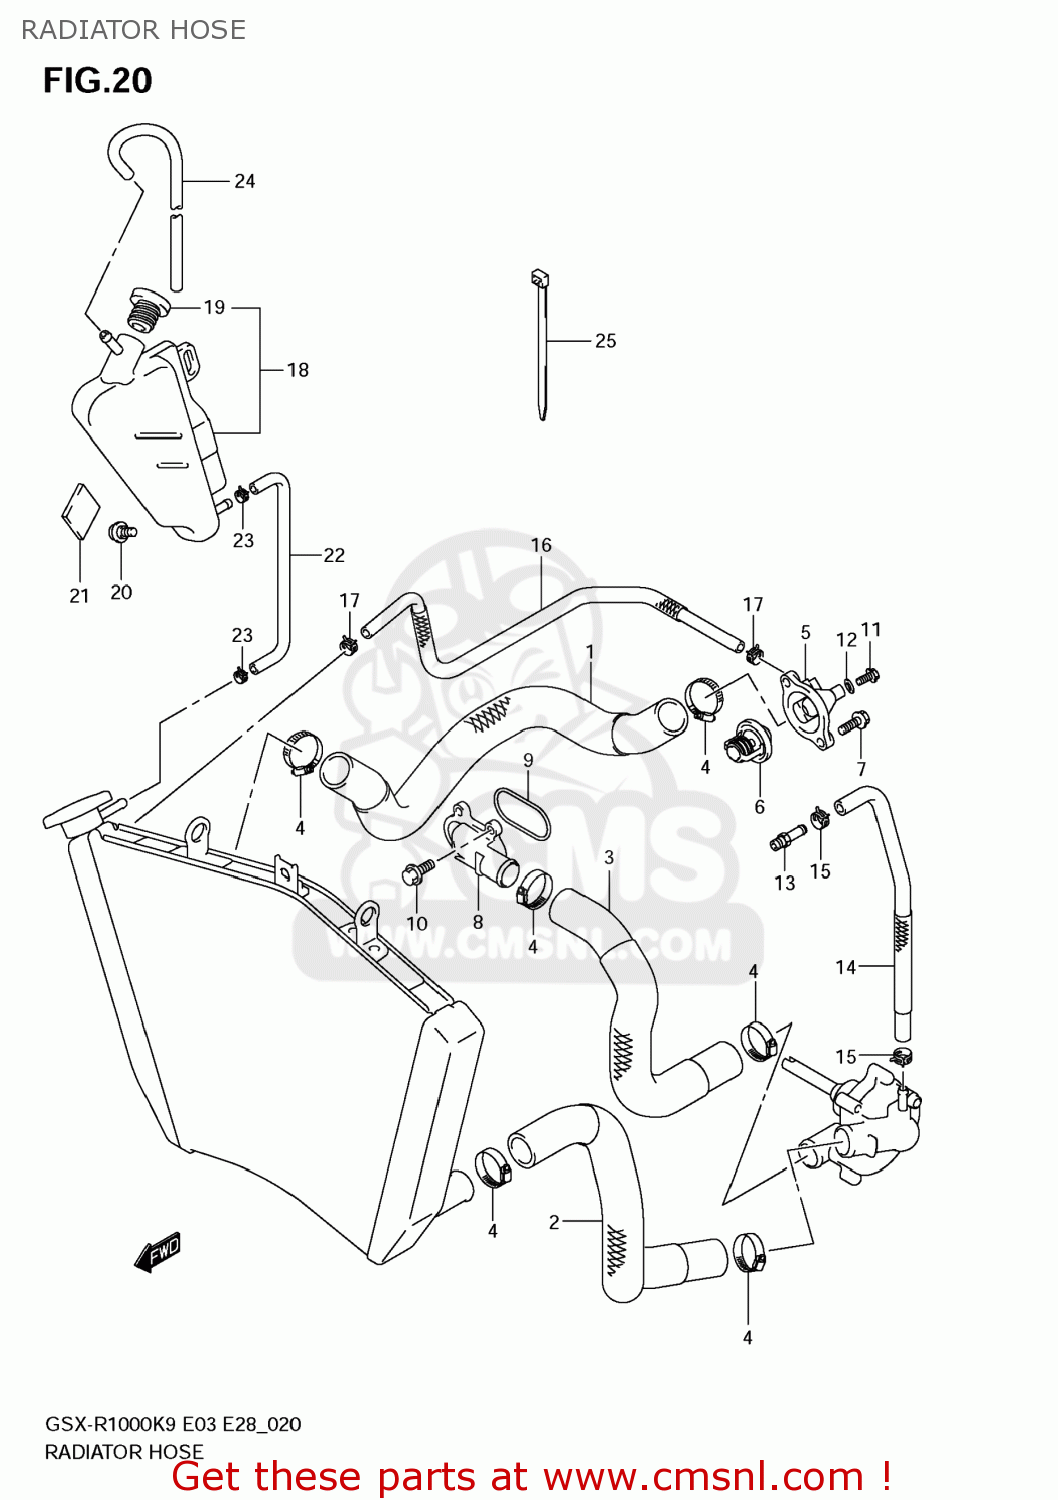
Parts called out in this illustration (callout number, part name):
1	HOSE,RADIATOR INLET
2	HOSE,RADIATOR OUTLET
3	HOSE,CYLINDER INLET
4	CLAMP
5	COVER,THERMOSTAT
6	THERMOSTAT,WATER
7	BOLT
8	CONNECTOR,CYLINDER WATER INLET
9	O RING,CYL WATER CONNECTOR
10	BOLT
11	UNION BOLT,AIR VENT
12	GASKET(6.4X11.5X0.8) (NAS)
13	BOLT UNION
14	HOSE,WATER BYPASS
15	CLAMP
16	HOSE,WATER AIR BLEED
17	CLIP
18	TANK ASSY,RESERVOIR
19	CAP,RESERVOIR TANK
20	BOLT(6X12)
21	CUSHION
22	HOSE,RESERVOIR TANK INLET
23	CLIP
24	HOSE,RESERVOIR TANK OVFL
25	CLAMP(L:100)
